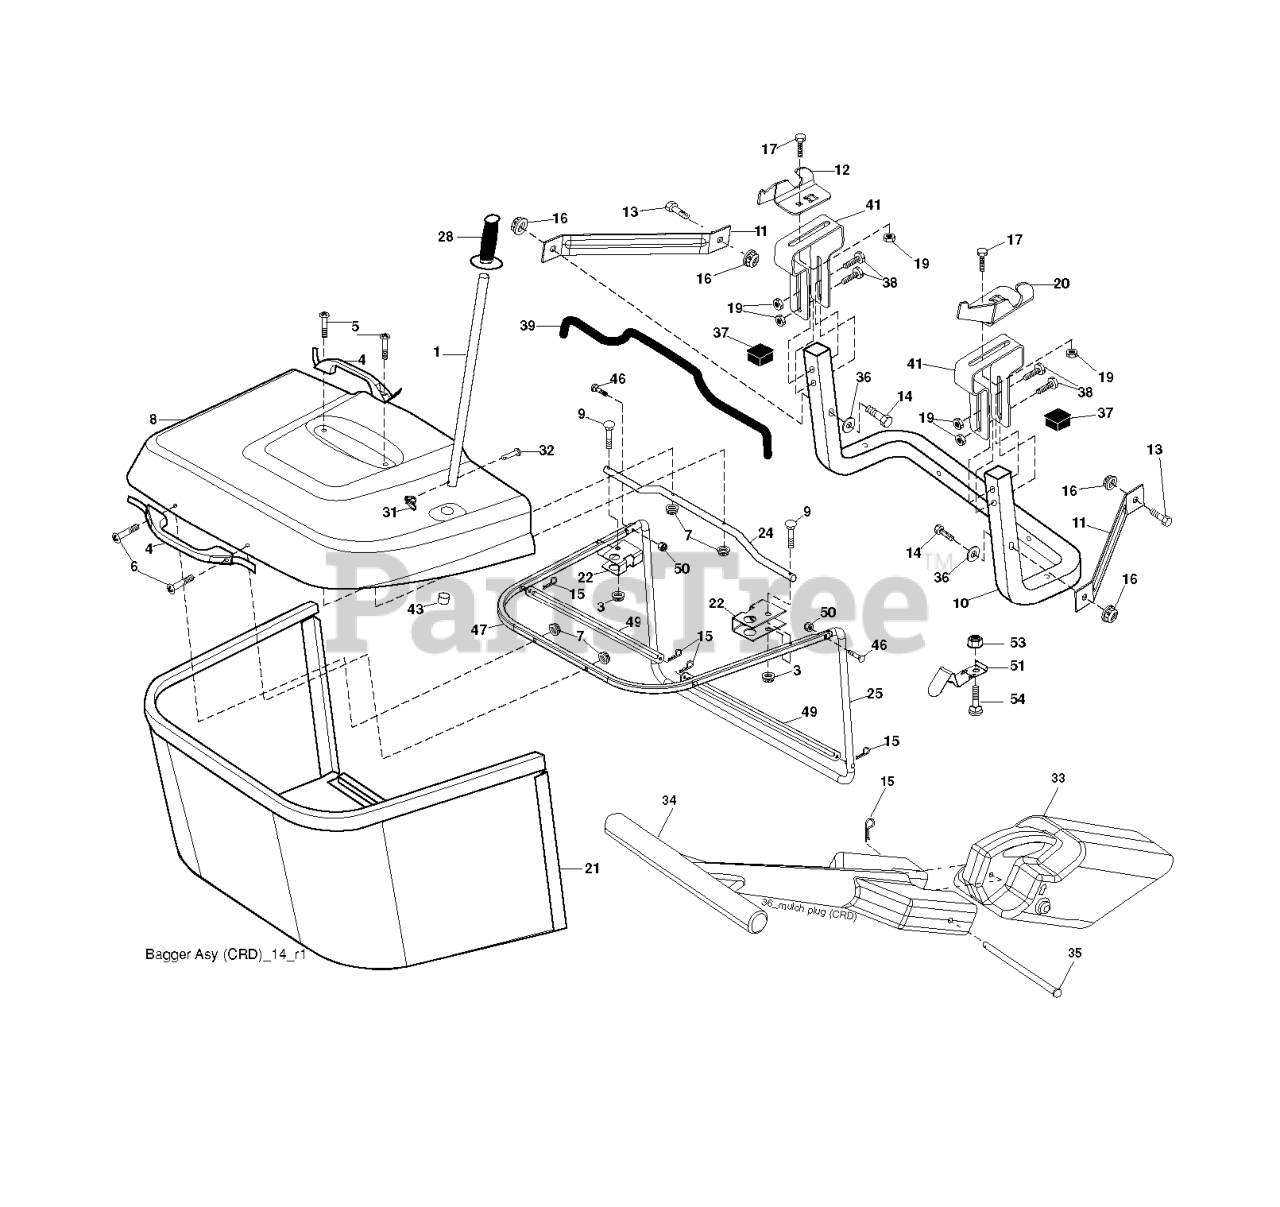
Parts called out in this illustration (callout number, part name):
1	TUBE HANDLE
3	NUT T
4	HANDLE.BAGGER.W/LVRS.BLK.CRD
5	SCREW.PAN.HEAD
6	REPL BY 532 75 00-29
8	COVER.PNT.BGR.CRD.WSLOTS.MS668
9	Bolt Carriage 1/4-20 x 2.25d x Gr.5
10	TUBE
11	BRACKET.SUPPORT.UPPER.BAG.CRD
12	BRKT PIVOT
14	BOLT-HEX EAK
15	RETAINER-SPRNG RB
16	NUT LOCK FLG 3/8-16 UNC
17	RP BOLT 5/16-18 X3/4 ZN/YEL GR
19	NUT LOCK HEX FLANGE 5/16-18
20	BRKT.PIVOT.RH.CRD
21	BAGGER.ASM.CRD.2007
22	BRKT.SIDE.BAG.CRD
24	TUBE.PIVOT.BAG.CRD.BLACK
25	PIPE
28	GRIP.HANDLE.BLACK
31	RETAINER CLIP
32	RIVET,DRILLED
33	PLUG.MULCHER.92 CRD
34	HANDLE.MULCHER.92.CRD (2 2)
36	WASHER
37	Plug Support Bagger CRD
38	BOLT.5/16-18X2.5
39	SEAL.BAGGER.CRD
41	BRKT.VERT.ADJ.BAGGER.CRD
43	PLUG, TUBING END
46	BOLT.CARRIAGE.5/16-18
47	PIPE
49	ROD
50	NUT.71038.31-18.HEX.NYLOCK
51	LATCH
53	NUT
54	BOLT
